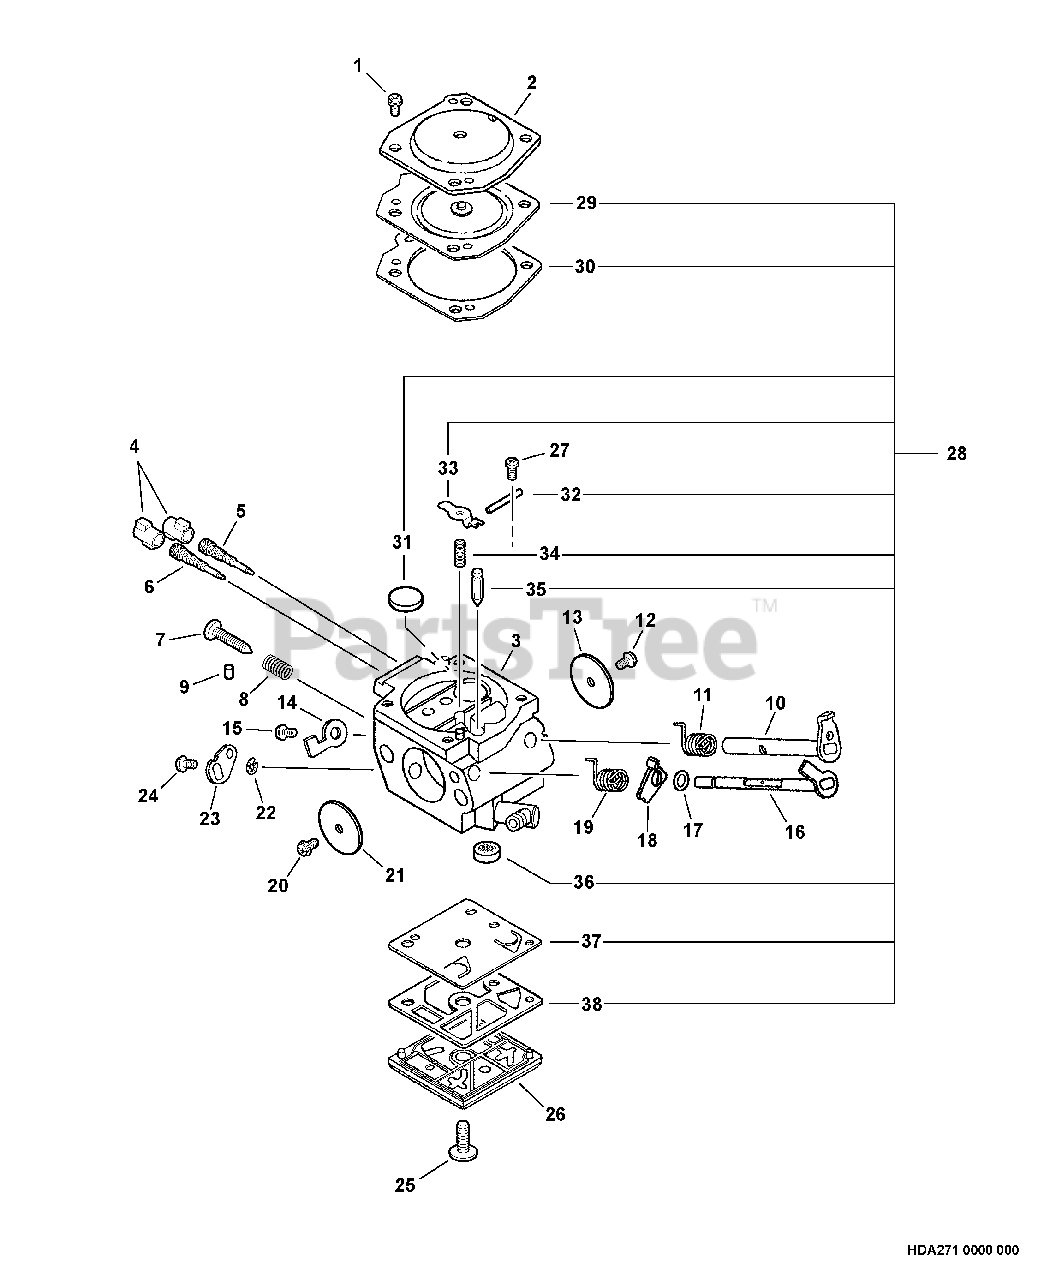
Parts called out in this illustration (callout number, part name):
2	COVER, METERING
3	BODY, CARBURETOR
4	CAP, LIMITER
5	NEEDLE - MIXTURE
6	NEEDLE - HIGH SPEED
7	SCREW, IDLE ADJUST
8	SPRING, IDLE ADJUST
10	SHAFT, THROTTLE
11	SPRING, THROTTLE RETURN
13	VALVE, THROTTLE
14	STOP, THROTTLE
16	SHAFT, CHOKE
18	LEVER, FAST IDLE
19	SPRING, CHOKE RETURN
21	VALVE, CHOKE
22	RING, RETAINING
23	LEVER, CHOKE
25	SCREW, PUMP COVER
26	COVER, PUMP
27	SCREW, METERING LEVER PIN
28	REPAIR KIT
29	DIAPHRAGM, METERING
30	GASKET, DIAPHRAGM
31	PLUG, WELCH
32	PIN, METERING LEVER
33	LEVER, METERING
34	SPRING, METERING LEVER
35	VALVE, INLET NEEDLE
36	STRAINER
37	DIAPHRAGM, PUMP
38	GASKET, PUMP
